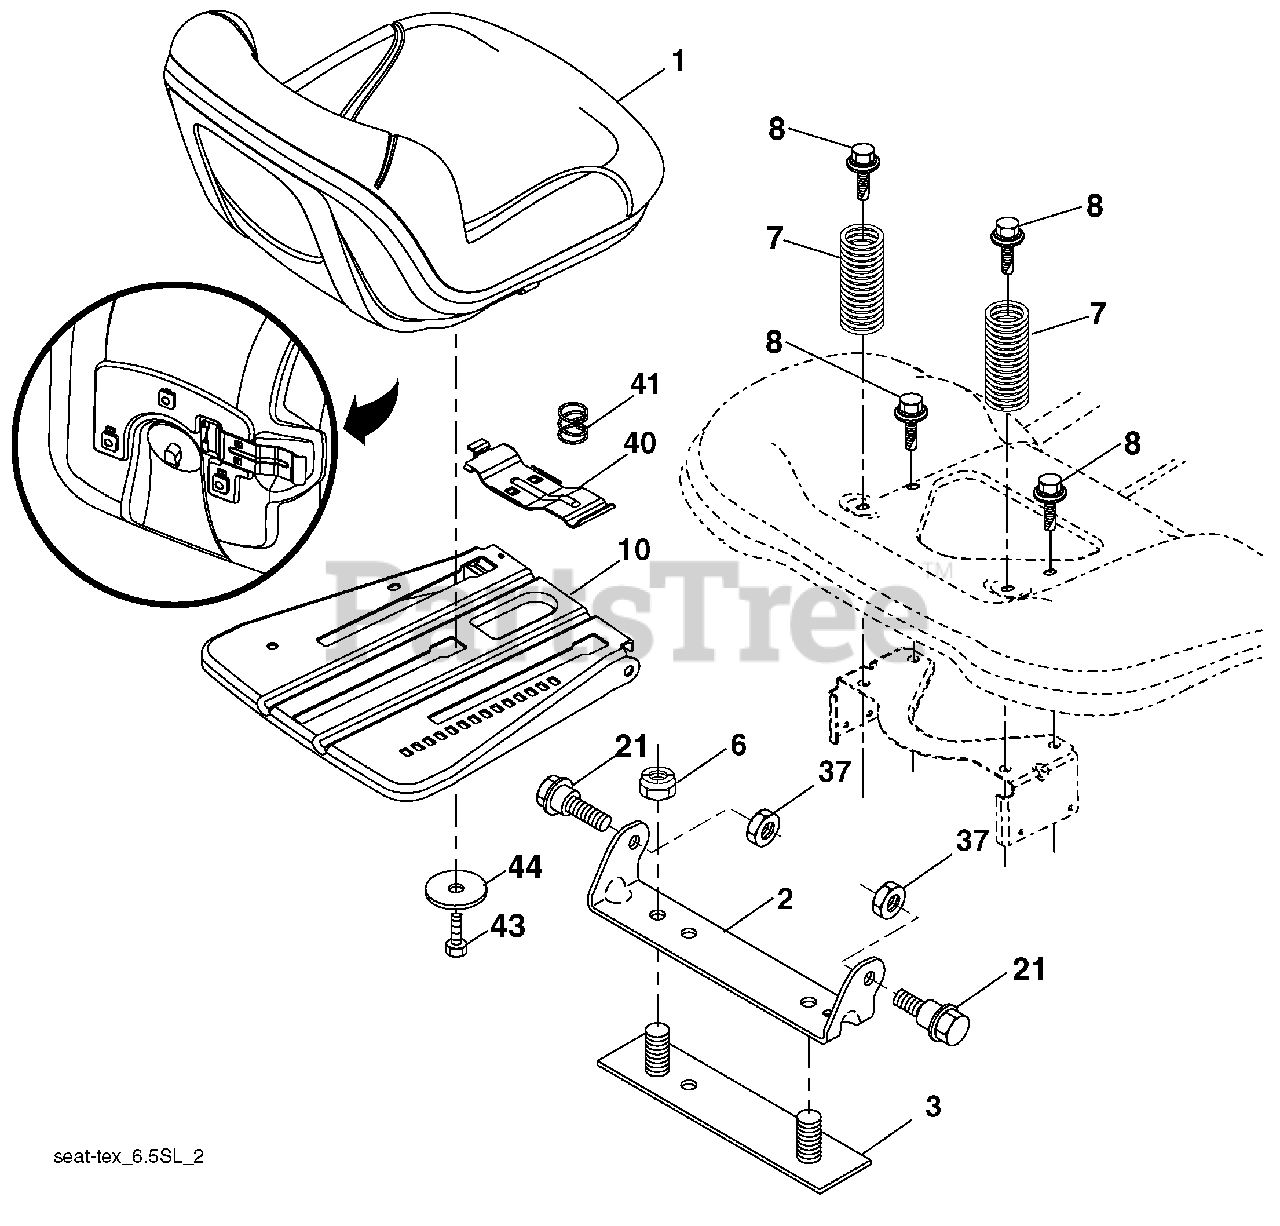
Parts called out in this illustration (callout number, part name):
1	Seat
2	Bracket Pivot Fender
3	Strap, Asm Fender
6	Nut, Lock w/Ins. 3/8-16 unc
7	Spring, Seat Cprsn
8	Bolt 5/16-18 unc x 3/4 w/Sems
10	Pan, Seat
21	Bolt, Shoulder 5/16-18
37	Nut, Lock 5/16-18 unc
40	Handle Slide
41	Spring Latch
43	Bolt 3/8-16 unc x 3/4
44	Washer 13/32 x 2 3/8 x 12 Ga.
